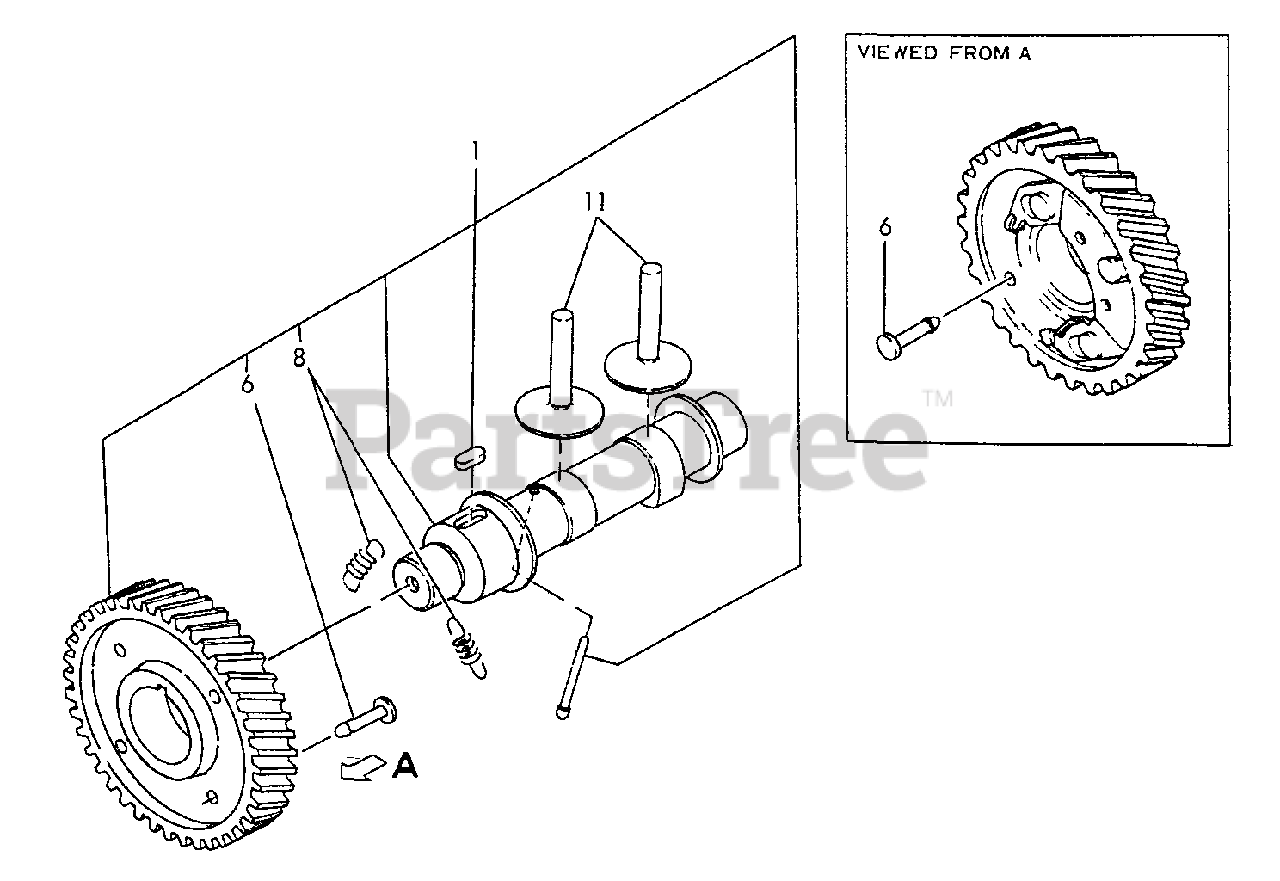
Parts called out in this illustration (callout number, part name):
1	CAMSHAFT ASSY
6	PIN
8	SPRING
11	TAPPET
